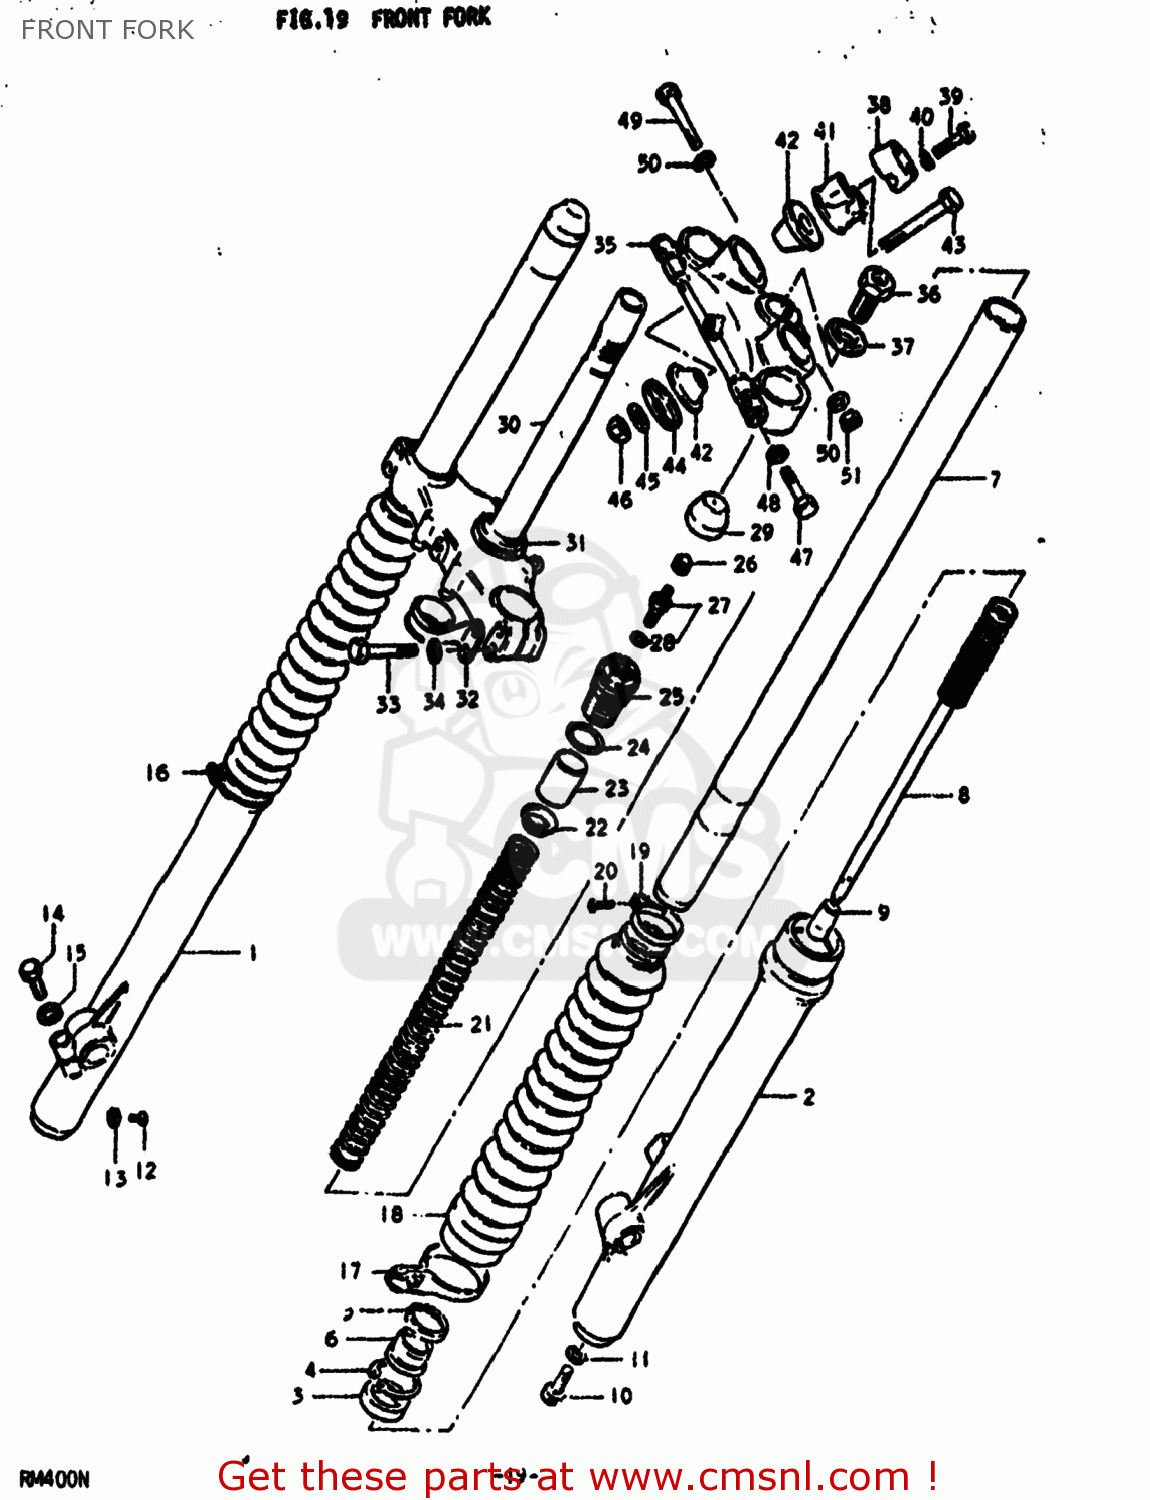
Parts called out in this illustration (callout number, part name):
1	TUBE,OUTER,RIGHT
2	TUBE,OUTER,LEFT
3	SEAL,OIL
4	CIRCLIP,FORK OIL SEAL
5	CASE,DUST SEAL FRONT FORK
6	DUST SEAL,FRONT FORK
7	TUBE,FORK,INNER
8	CYLINDER,FRONT FORK
9	PIECE,OIL LOCK
10	BOLT,CYLINDER
11	GASKET,CYLINDER (NAS)
12	SCREW
13	GASKET,DRAIN,PLUG (NAS)
14	BOLT (8X30)
15	LOCK WASHER
16	BAND,FRONT FORK COVER BOOT
17	BAND,FRONT FORK COVER BOOT
18	BOOT
19	BAND,BOOT
20	SCREW
21	SPRING
22	GUIDE
23	COLLAR,SPRING
24	O RING
25	CAP,FORK INNER TUBE
26	CAP,VALVE
27	VALVE
28	O RING
29	CAP
30	STEM,STEERING
31	RACE,STEERING,OUTER,UPPER
32	GUIDE,CABLE
33	BOLT 8X45
34	WASHER,LOCK,8.
35	HEAD,STEERING STEM
36	BOLT
37	WASHER
38	HOLDER,HANDLEBAR
39	BOLT 8X45
40	LOCK WASHER
41	HOLDER,HANDLEBAR,LOWER
42	CUSHION,HANDLE HOLDER
43	BOLT,HANDLE HOLDER
44	COVER,HANDLEBAR HOLDER
45	WASHER,HANDLEBAR HOLDER
46	NUT
47	BOLT
48	LOCK WASHER
49	BOLT 8X50
50	WASHER
51	NUT
